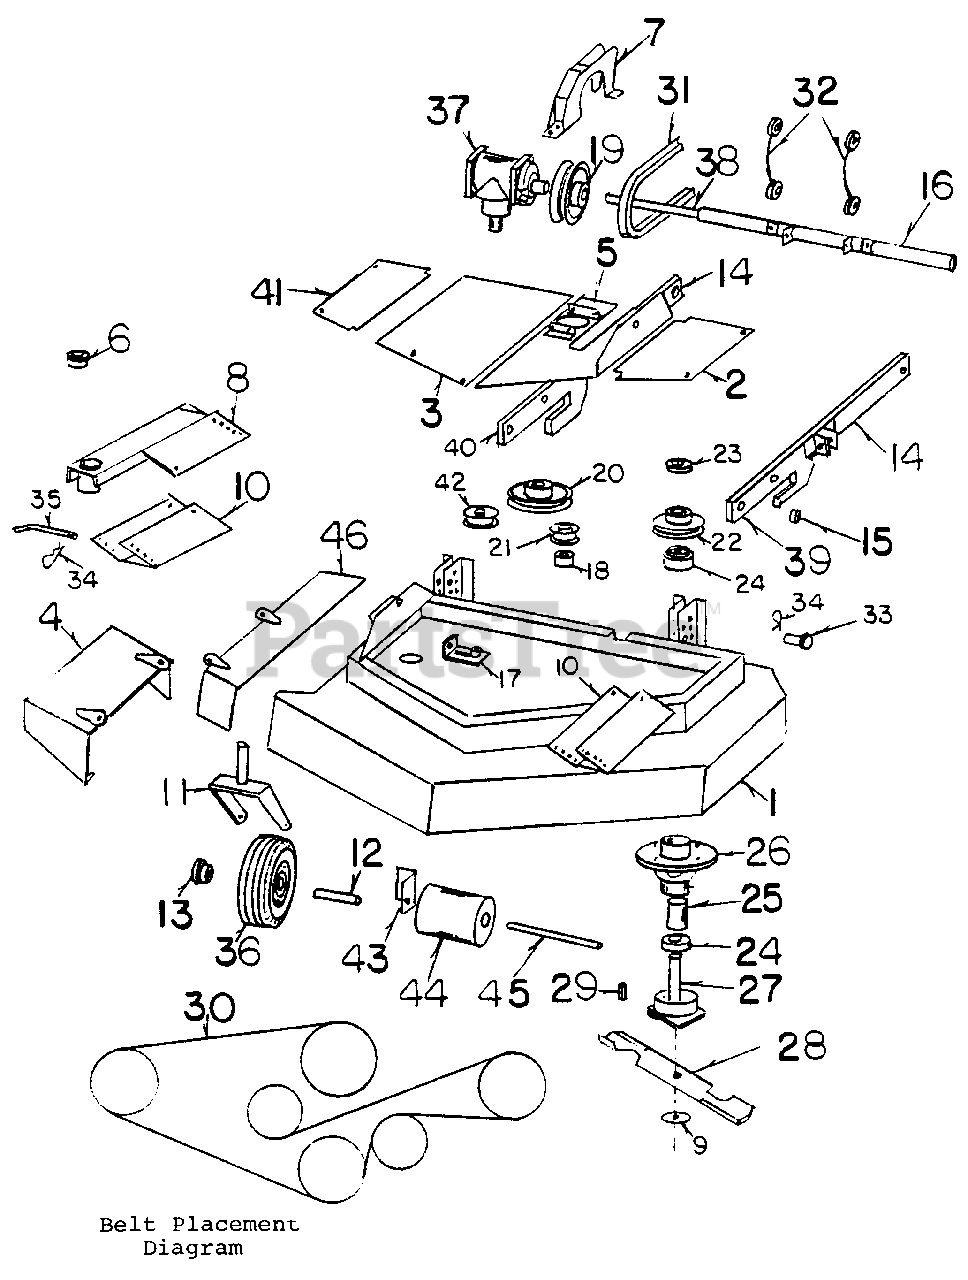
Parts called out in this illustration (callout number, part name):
1	MOWER DECK
2	COVER (Small)
3	COVER (Large)
4	FOOT GUARD
5	GEAR BOX MOUNT
6	GAGE WHEEL MOUNT
7	BELT GUARD
8	GAGE WHEEL MOUNT
9	SPRING WASHER
10	BRACKET, GAGE WHEEL MOUNT
11	FORK, GAGE WHEEL
12	AXLE, GAGE WHEEL
13	WHEEL BEARING
14	DECK LIFT ARM BACK ADJUSTABLE FR18
14	DECK LIFT ARM BACK ADJUSTABLE FR18C
15	BUSHING, DECK LIFT ARM
16	CROSSBAR
17	BELT TIGHTENER
18	SPACER IDLER
19	PULLEY, GEAR BOX (Input)
20	PULLEY, GEAR BOX (Output)
21	PULLEY, IDLER (Small)
22	PULLEY, SPINDLE
23	WASHER, SPINDLE
24	BEARING, SPINDLE
25	SPACER, SPINDLE
26	HOUSING, SPINDLE
27	SHAFT, SPINDLE
29	KEY, SPINDLE
30	DECK BELT
31	DRIVE BELT FR18
31	DRIVE BELT FR18C
32	CABLE, DECK
33	PINS, DECK
34	HAIR PINS
35	PINS, GAGE WHEEL
36	GAGE WHEEL
37	GEAR BOX
38	CROSSBAR PIN
39	L.H. 1 DECK LIFT ARM FRONT ADJUSTABLE
40	R.H. 1 DECK LIFT ARM FRONT ADJUSTABLE
41	COVER, RIGHT HAND SIDE
42	PULLEY, IDLER (Large)
43	RUBBER ROLLAR
44	RUBBER ROLLAR
45	ROLLAR SHAFT
46	FOOT GUARD MOUNT
